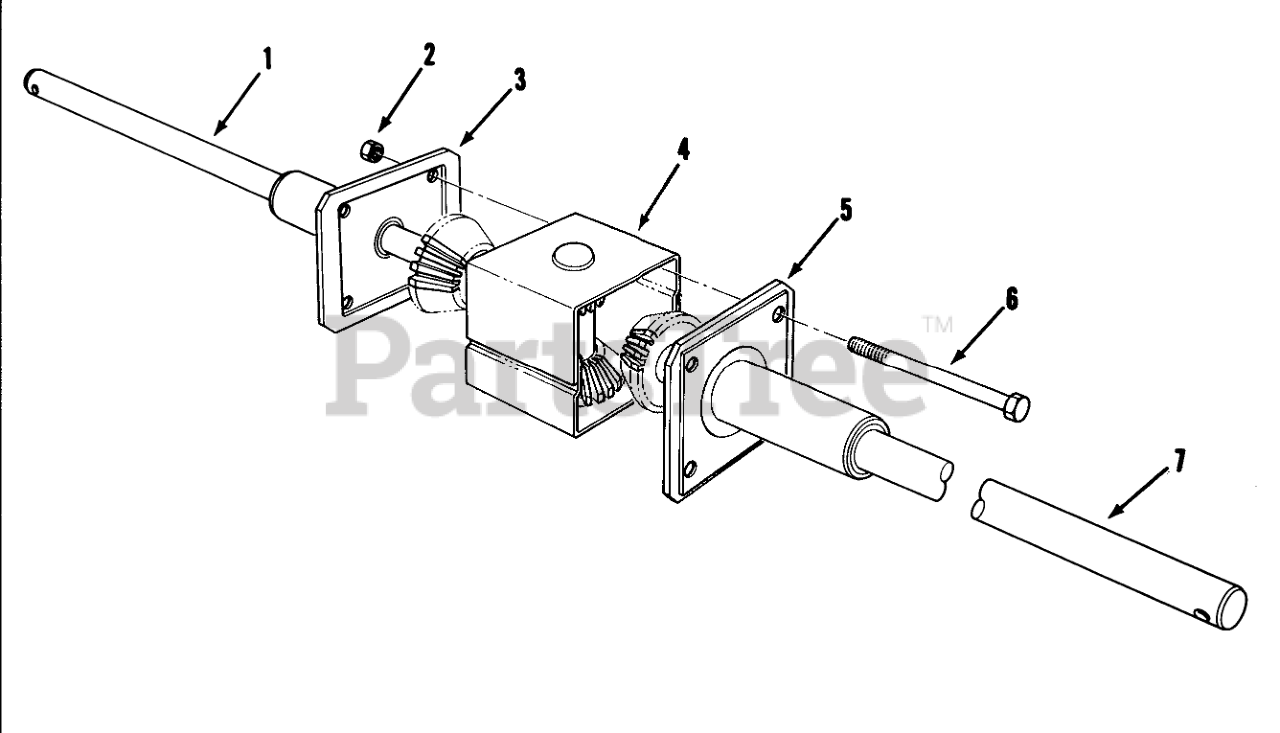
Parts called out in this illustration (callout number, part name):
2	NUT-LOCK, CONE
3	END CAP/BRG ASM
4	GEAR CASE ASM
5	END CAP &BEARING ASY
6	SCREW-HH
